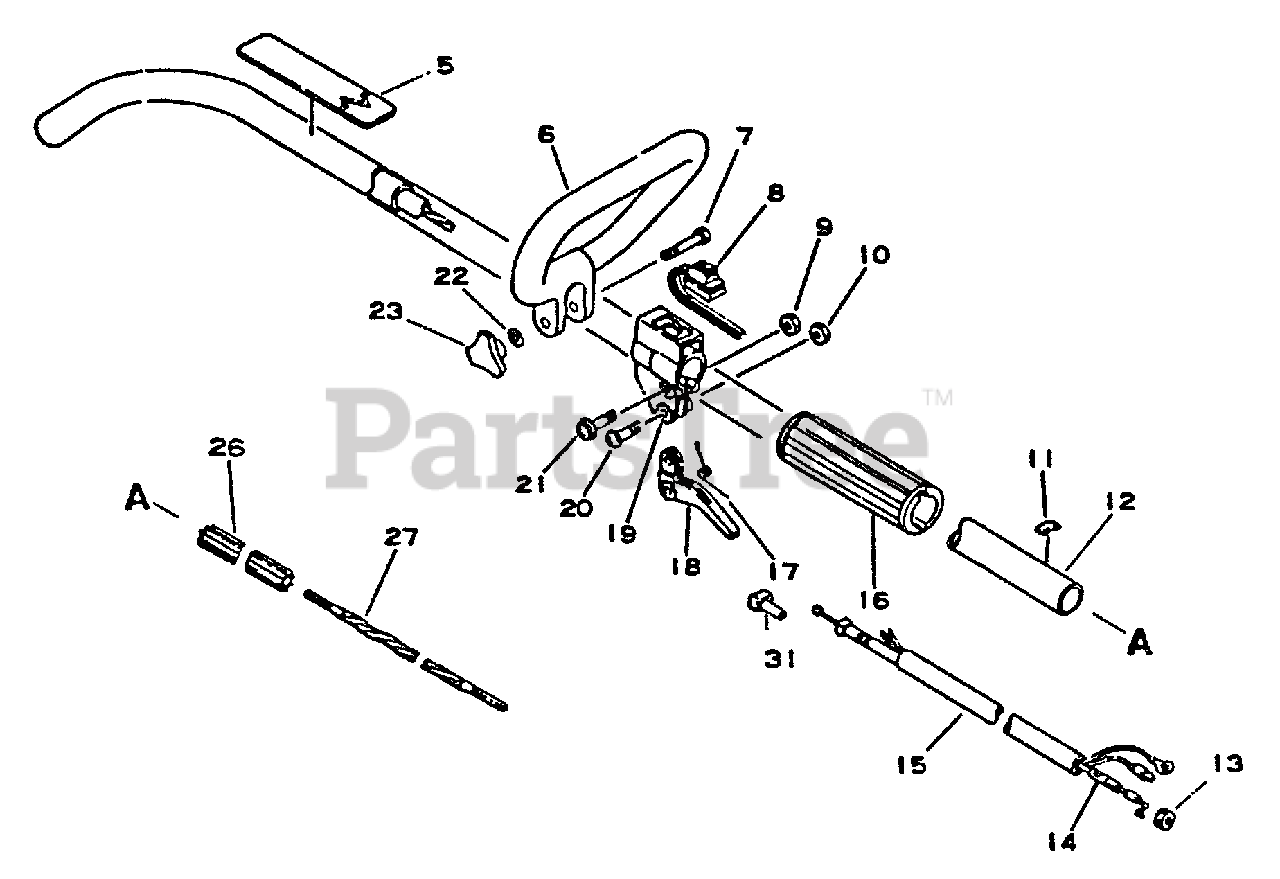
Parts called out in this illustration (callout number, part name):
5	LABEL - CAUTION
6	HANDLE
7	BOLT - 6×40
8	IGNITION SWITCH ASSY
9	NUT M5
10	LOCKNUT - 5
11	LABEL - ALIGNMENT
12	MAIN PIPE ASSY
14	CABLE, THROTTLE
16	GRIP, HANDLE
17	SPRING, THROTTLE
18	TRIGGER, THROTTLE
19	BRACKET, THROTTLE CONTROL
21	SCREW 5×28
22	WASHER 6.5×11.5×0.8
23	KNOB, FASTENER
26	LINER - FLEXIBLE
27	DRIVESHAFT - FLEXIBLE
31	GUIDE, CABLE
